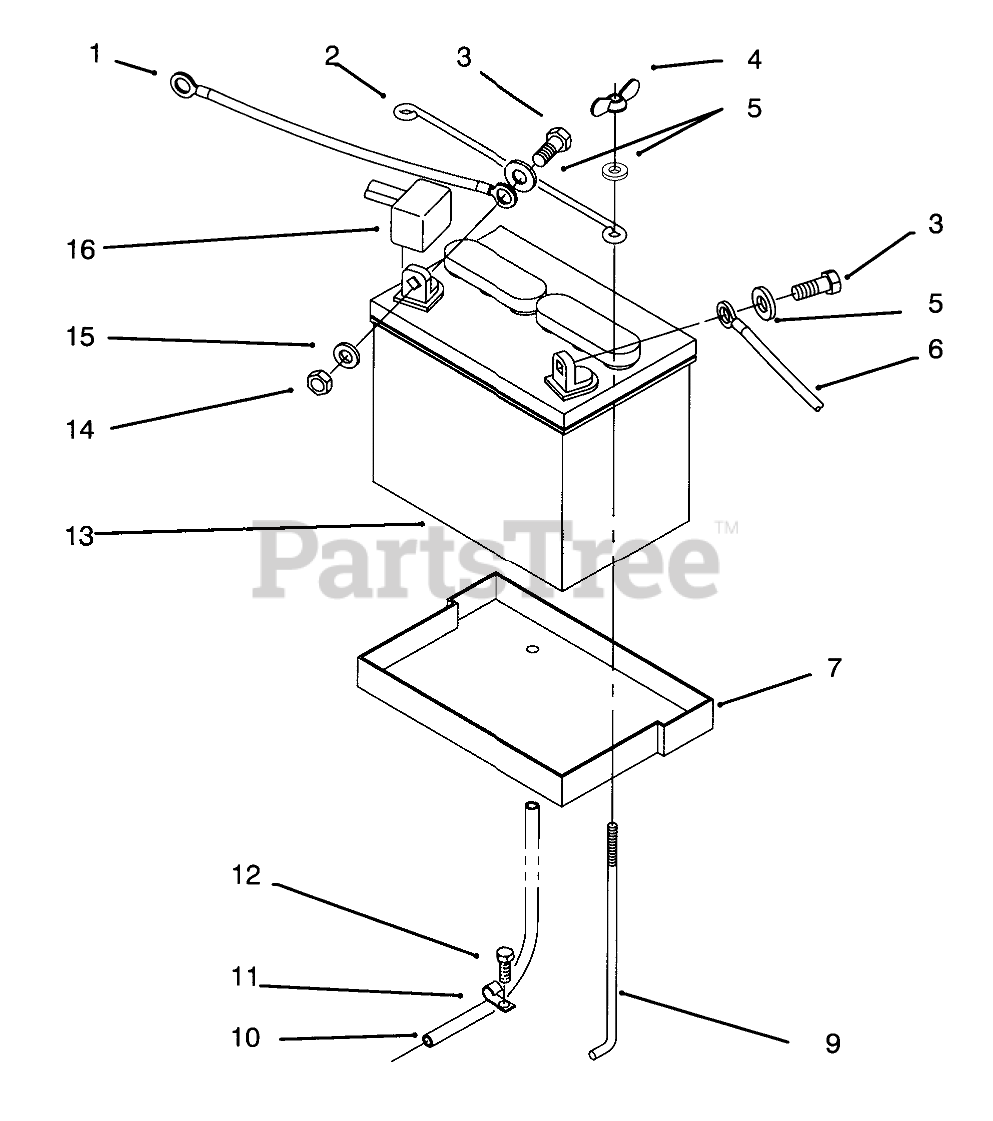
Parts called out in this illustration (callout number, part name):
1	CABLE-BLACK
2	HOLDDOWN-BATTERY
3	SCREW-HH
4	NUT-WING
5	WASHER-FLAT
6	ASSY WIRE
7	TRAY-BATTERY
9	HOOK-BATTERY RETAIN
10	TUBE-21" BATTERY DRAIN
11	CLIP
12	SCREW-HH
13	Battery
14	NUT-LOCK, NI
15	WASHER-LOCK
16	Boot
